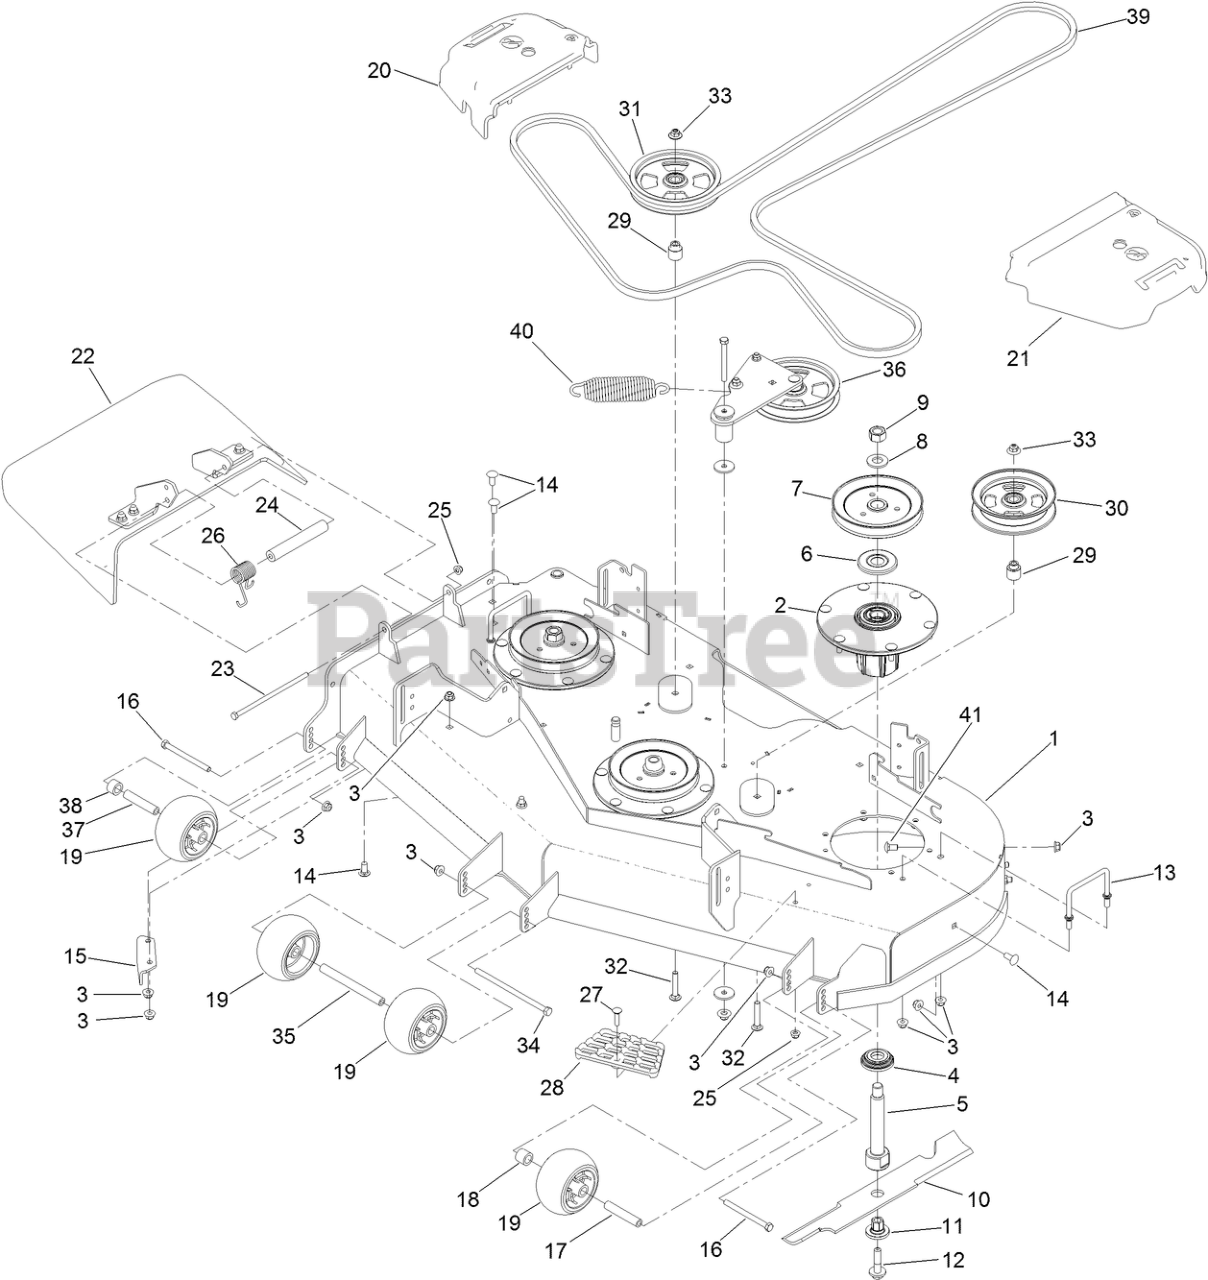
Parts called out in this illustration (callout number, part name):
1	DECK DECAL ASM
2	SPINDLE ASM
3	NUT-HF, NI
4	GUARD-BOTTOM
5	SHAFT-SPINDLE
6	GUARD-BEARING, TOP
7	SHEAVE-BLADE DRIVE 6.50
8	WASHER
9	NUT-HEX
10	BLADE-FLOW, HIGH
11	BUSHING-HEX
12	SCREW-SEMS
13	WIREFORM-COVER
14	SCREW-CARR
15	BAFFLE-DISCHARGE
16	SCREW-HH
17	TUBE-SPANNER
18	TUBE-SPACER
19	ROLLER-SCALP, ANTI
20	COVER-BELT, RH
21	COVER-BELT, LH
22	RUBBER DEFLECTOR ASM
23	SCREW-HH
24	SPACER
25	NUT-HF, NI
26	SPRING-TORSION
27	SCREW-CARR
28	STEP-DECK
29	BUSHING, IDLER
30	PULLEY-IDLER, FLAT
31	PULLEY-IDLER, FLAT
32	SCREW-CARR
33	NUT-FLANGE, NI
34	SCREW-HH
35	SPACER-WHEEL
36	IDLER ARM ASM
37	TUBE-SHAFTING
38	TUBE-SPACER
39	BELT-V
40	SPRING-EXTENSION
41	SCREW-CARR
